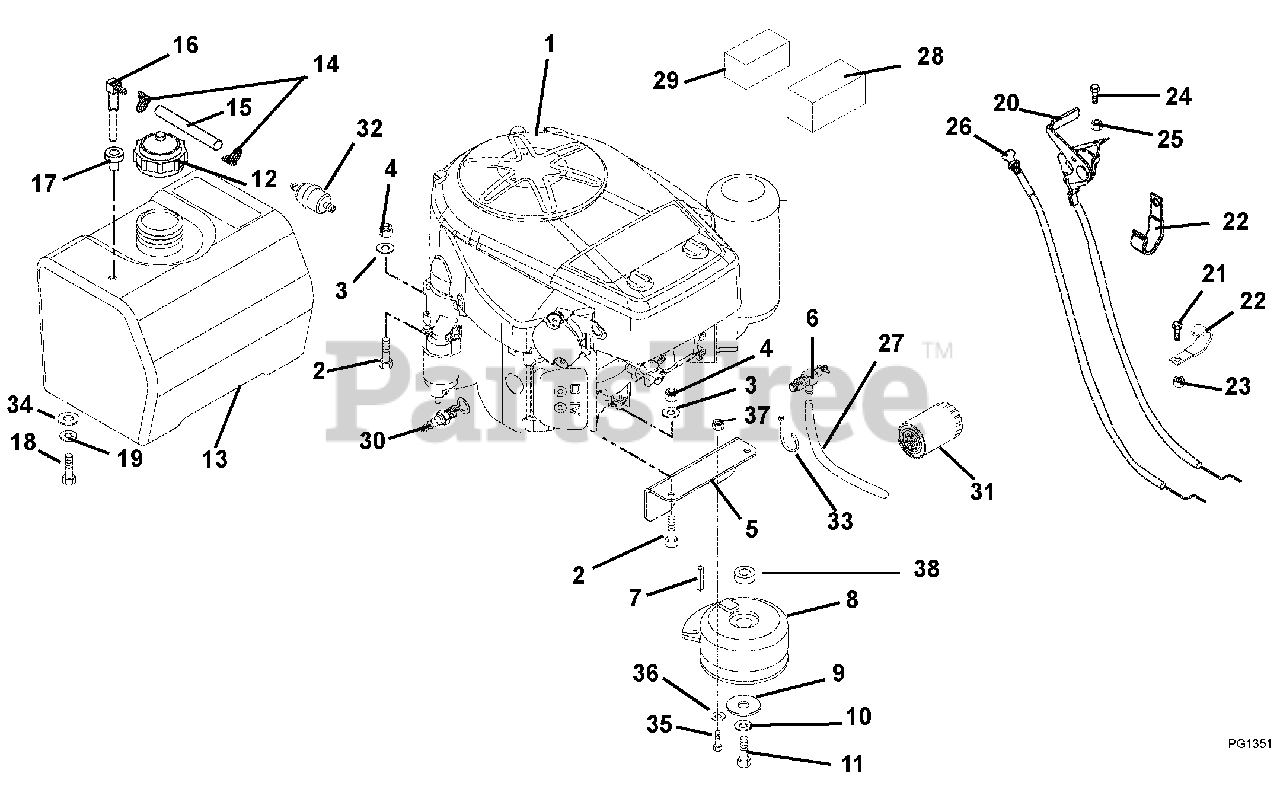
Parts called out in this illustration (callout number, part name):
1	Engine, 15 HP Kawasaki FH430V - AS02 (105, 120)
2	Bolt-Hex .31-18 x 1.75 Grade 5
3	Washer-Locking .31 x .078 Regular
4	Nut-Hex .31-18
5	Bracket, Clutch
6	Valve, Oil Drain
7	Key-Square .25 x 1.25 x 25 SAE 8630 OR SAE 1035
8	Clutch, Electric PTO
9	Washer-Flat-Steel .469 x 2.00 x .25
10	Washer-Locking .44 x .109 Regular
11	Bolt-Hex .44-20 x 3.00 Grade 5
12	Cap, Fuel
13	Tank, Fuel
14	Clamp-Hose Wire .49/.51 x .116
15	Gas Line-Bulk .25 I.D.
16	Fitting, Tank
17	Bushing (Black in color. Does not replace or interchange with orange colored grommet.)
18	Bolt-Hex .38-16 x .75 Grade 5
19	Washer-Locking .38 x .094 Regular
20	Cable, Throttle-with Liner (105, 108, 123, 124, 125, 126, 127)
21	Bolt-Hex .31-18 x .75 Grade 5
23	Nut-Locking-Nylon .312-18
24	Screw-Machine 10-24 x .75 Hex Washer Head
25	Nut-Locking-Nylon 10-24 with Insert
26	Control, Choke
27	Tube, Oil Drain
28	Filter, Air Paper (105, 120)
29	Filter, Air Foam (105, 120)
30	Spark Plug
31	Filter, Oil
32	Fuel Filter- Kawasaki
33	Cable Tie
34	Washer, Flat Steel .409 x .812 x .065
35	Bolt, Hex .31-18 x 1.25 Grade 5
36	Washer, Flat-Steel .344 x .688 x .065
37	Nut, Jam .31-18
38	Bushing, Spacer 1.0 x 1.25 x .25
